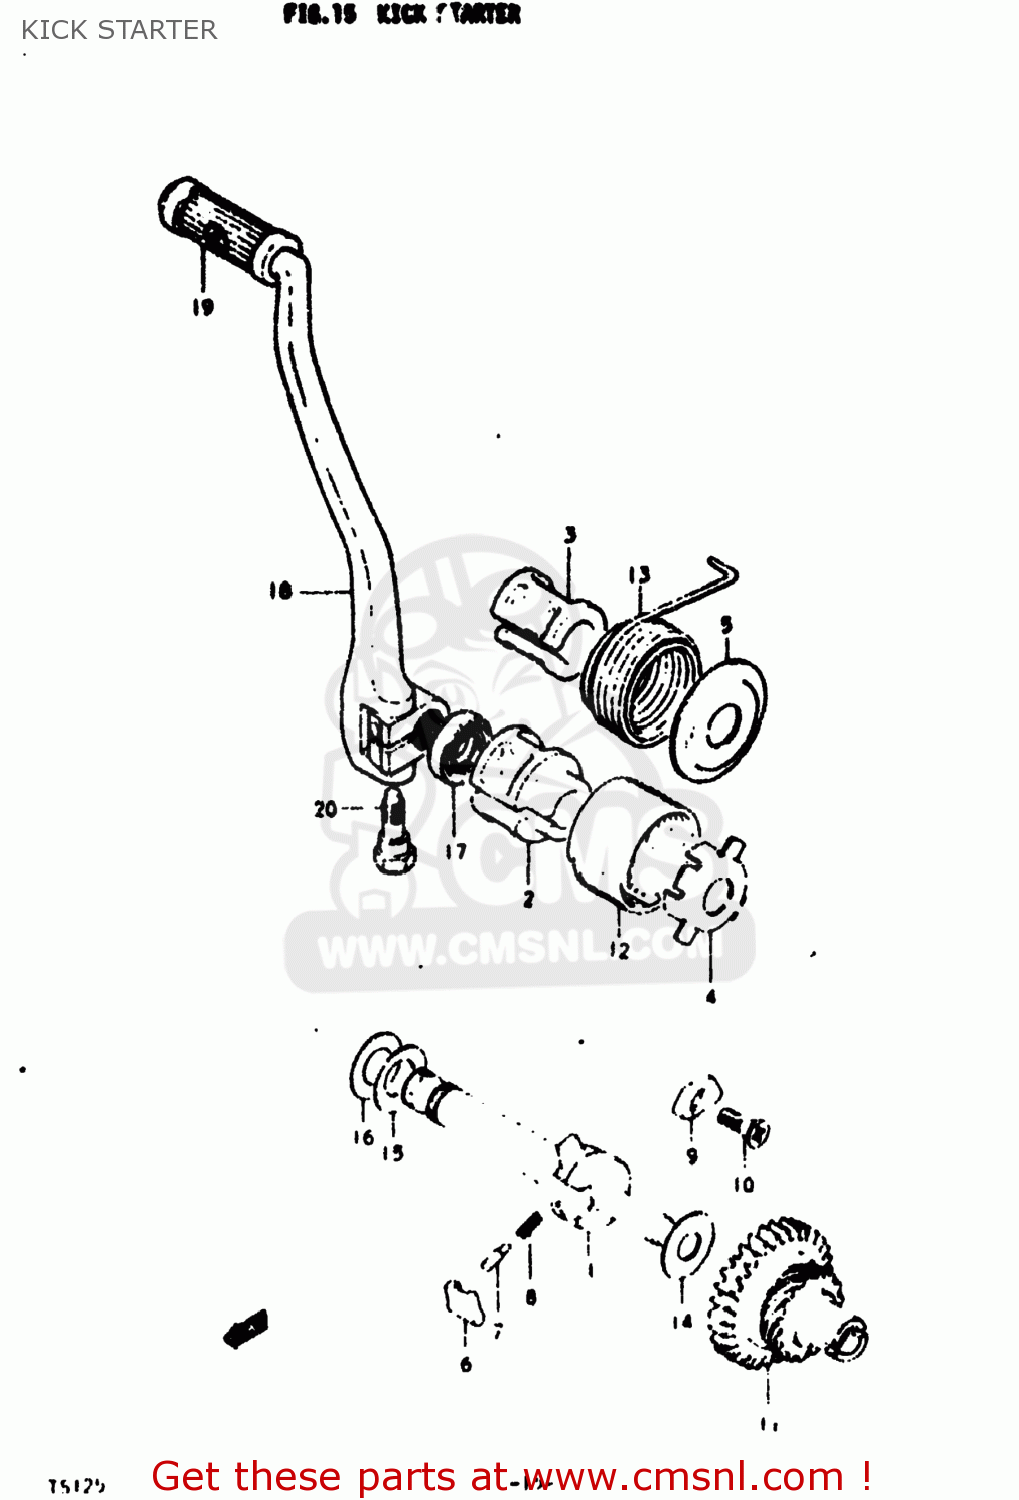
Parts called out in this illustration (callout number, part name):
1	SHAFT,KICK STARTER
2	GUIDE,KICK SHAFT SPRING
3	GUIDE,KICK STARTER SFT SPRING
4	HOLDER,KICK SHAFT SPRING
5	HOLDER,KICK STARTER SHAFT SPR
6	PAWL,KICK STARTER
7	PIN(5X15.5)
8	SPRING
9	LIFTER,KICK STARTER PAWL
10	SCREW(6X19)
11	GEAR,KICK STARTER DRIVE
12	SPRING
13	SPRING
14	WASHER
15	WASHER(16X30X0.5)
16	WASHER
17	SEAL,OIL(16X30X8)
18	LEVER ASSEMBLY,KICK STARTER
19	RUBBER,KICK STARTER PEDAL
20	BOLT
